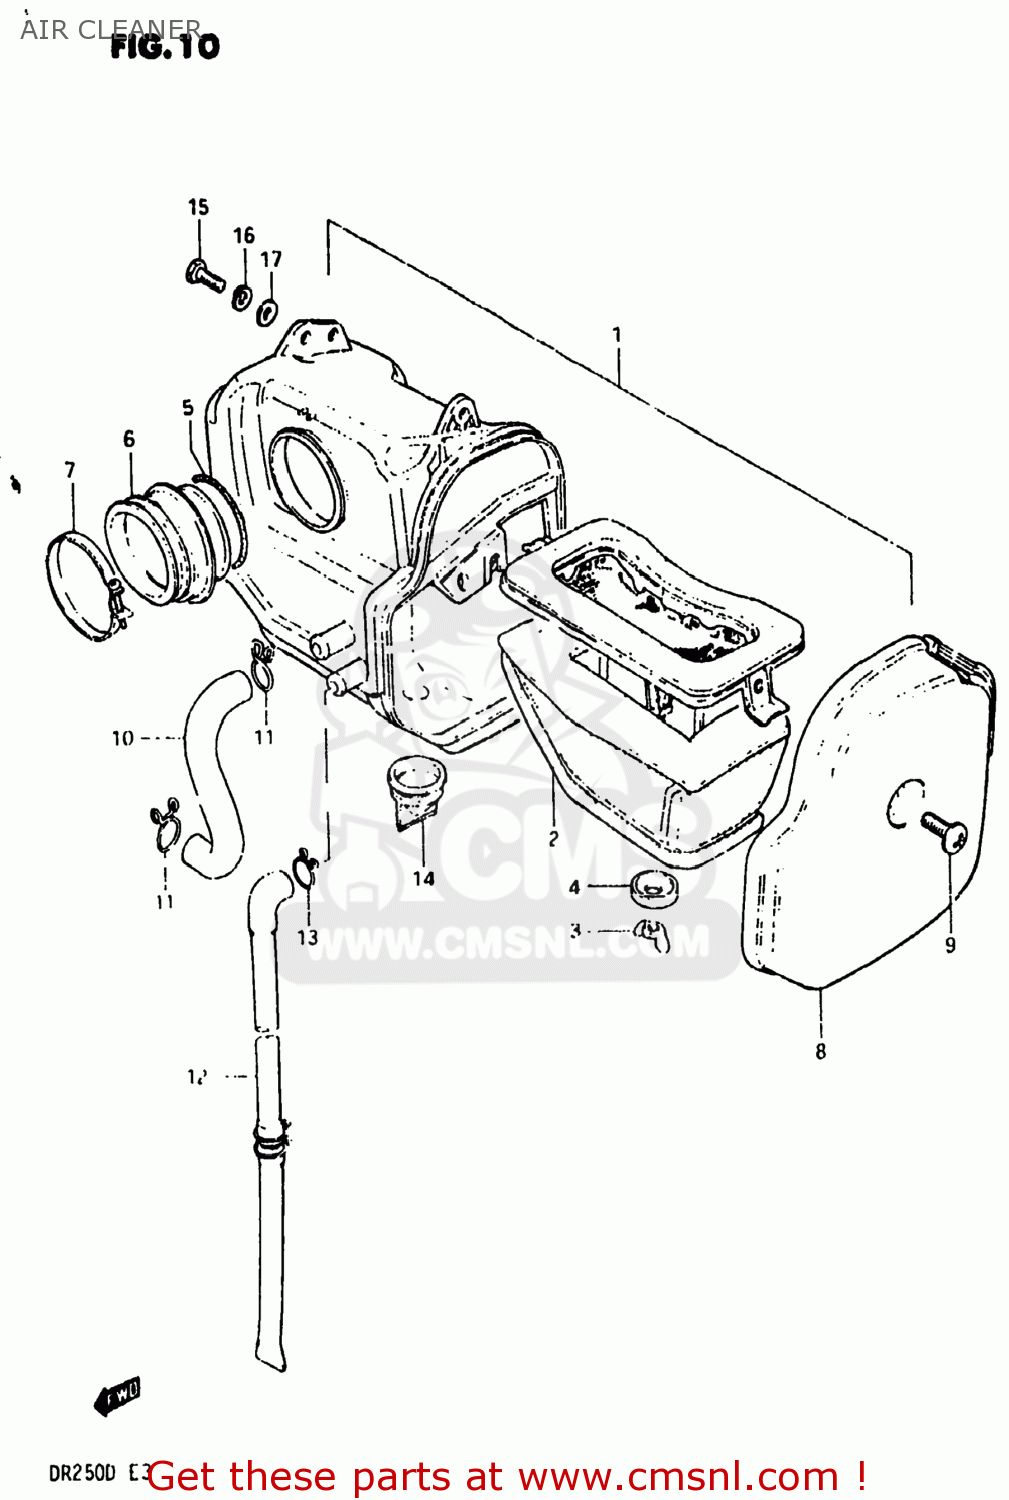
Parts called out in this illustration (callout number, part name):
1	CLEANER ASSEMBLY,AIR
2	ELEMENT,AIR CLEANER
3	NUT
4	WASHER
5	CLAMP,CLEANER SIDE
6	TUBE,AIR CLEANER OUTLET
7	CLAMP
8	CAP
9	SCREW
10	TUBE,BREATHER
11	CLAMP
12	DRAIN TUBE
13	CLAMP
14	HOSE,AIR CLEANER DRAIN
15	BOLT, UPPER
16	LOCK WASHER
17	WASHER
